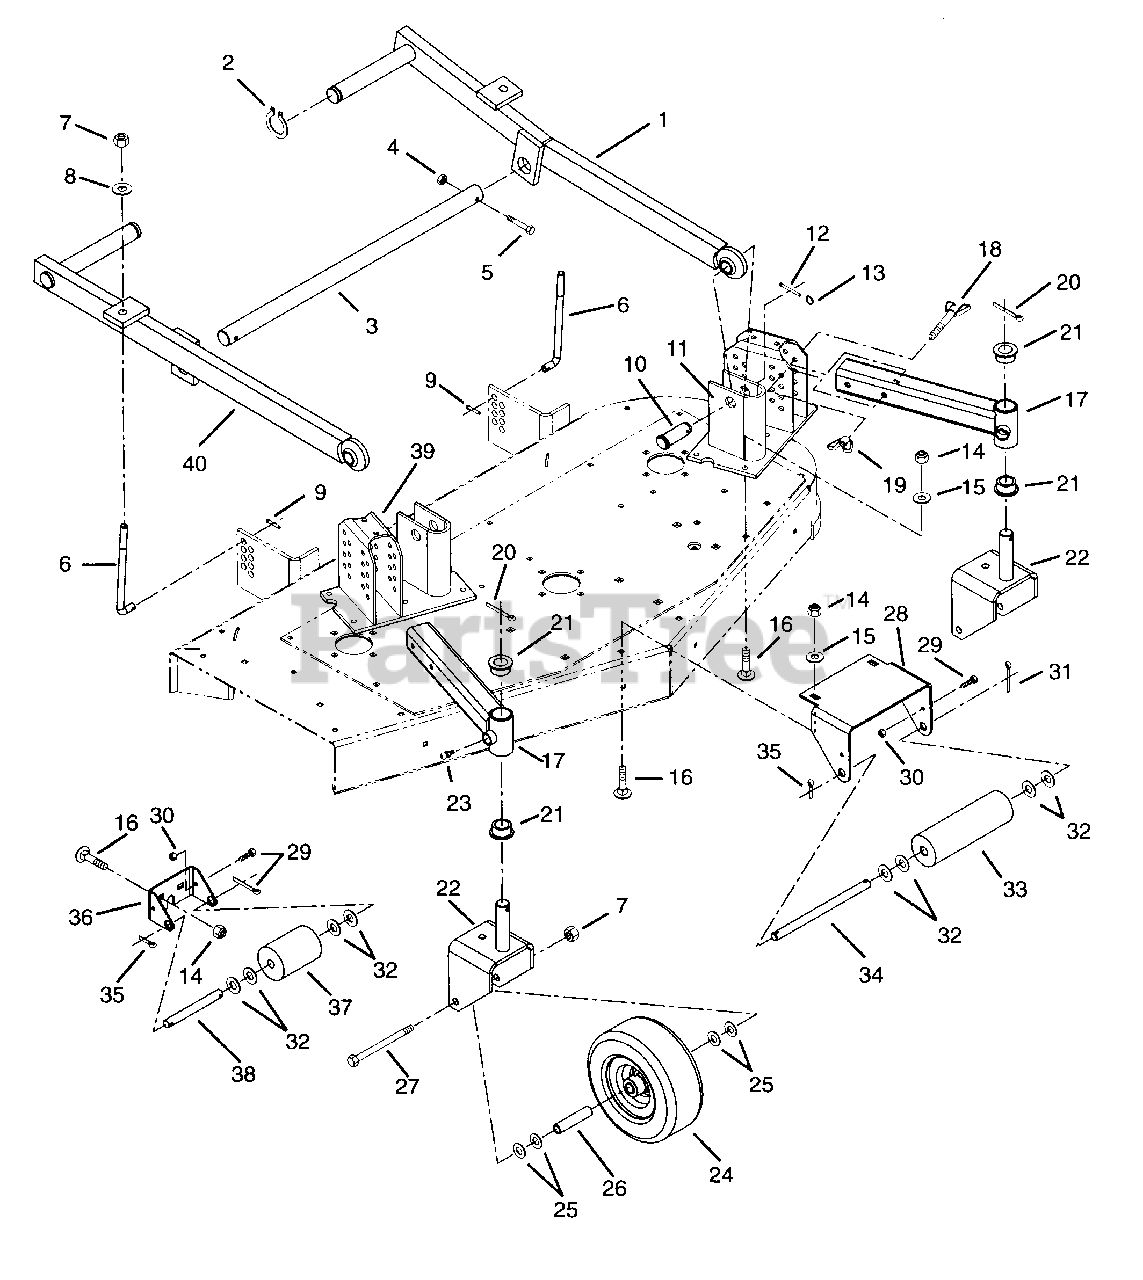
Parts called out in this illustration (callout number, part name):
1	Weldment, Lift Arm Left Hand
2	Ring-Retaining-External 1.150 x .093
3	Shaft, Mower Lift
4	Nut-Locking-Jam-Center .375-16
5	Bolt-Hex .25-20 x 1.75 Grade 2
6	Rod, Rear Height Adjustment
7	Nut-Locking-Nylon .50-13 Grade 5
8	Washer-Flat-Steel .531 x 1.250 x 1.00
9	Pin-Klik 1.000 x .188 x 1.25
10	Pin-Clevis .875 x 3.00
11	Weldment, Lift Arm Mount Left Hand
12	Pin-Clevis .313 x 2.62 Grade 5
13	Ring-Retaining-External 2.240 x .180
14	Nut-Locking-Nylon .375-16 Grade 2
15	Washer-Flat-Steel .406 x .812 x .065
16	Bolt-Round Head Square Neck .38-16 x 1.0
17	Caster Wheel Mount
18	Bolt, Wing 3/8-16 x 3
19	Nut, Wing 3/8-16
20	Pin-Cotter .188 x 1.625
21	Bushing-LFlange 1.020 x 1.385 x .75 x 1.75
22	Weldment, Caster Fork
23	Fitting-Lube .25-28 x .256
24	Wheel 9 x 3.50
25	Washer-Flat-Steel .500 x 1.250 x .083
26	Spacer .532 x .748 x 3.34
27	Bolt-Hex .50-13 x 5.50
28	Bracket, Roller Right Hand
29	Bolt-Hex .25-20 x .75 Grade 5
30	Nut-Locking-Nylon .250-20 Grade 2
31	Pin-Cotter .250 x 2.00
32	Washer-Flat-Steel .656 x 1.312 x .095
33	Roller, Gage
34	Shaft, Center Roller
35	Pin-Cotter .25 x 1.00
36	Bracket, Roller
37	Roller Gage
38	Rod
39	Weldment, Lift Arm Mount Right Hand
40	Weldment, Lift Arm Right Hand
